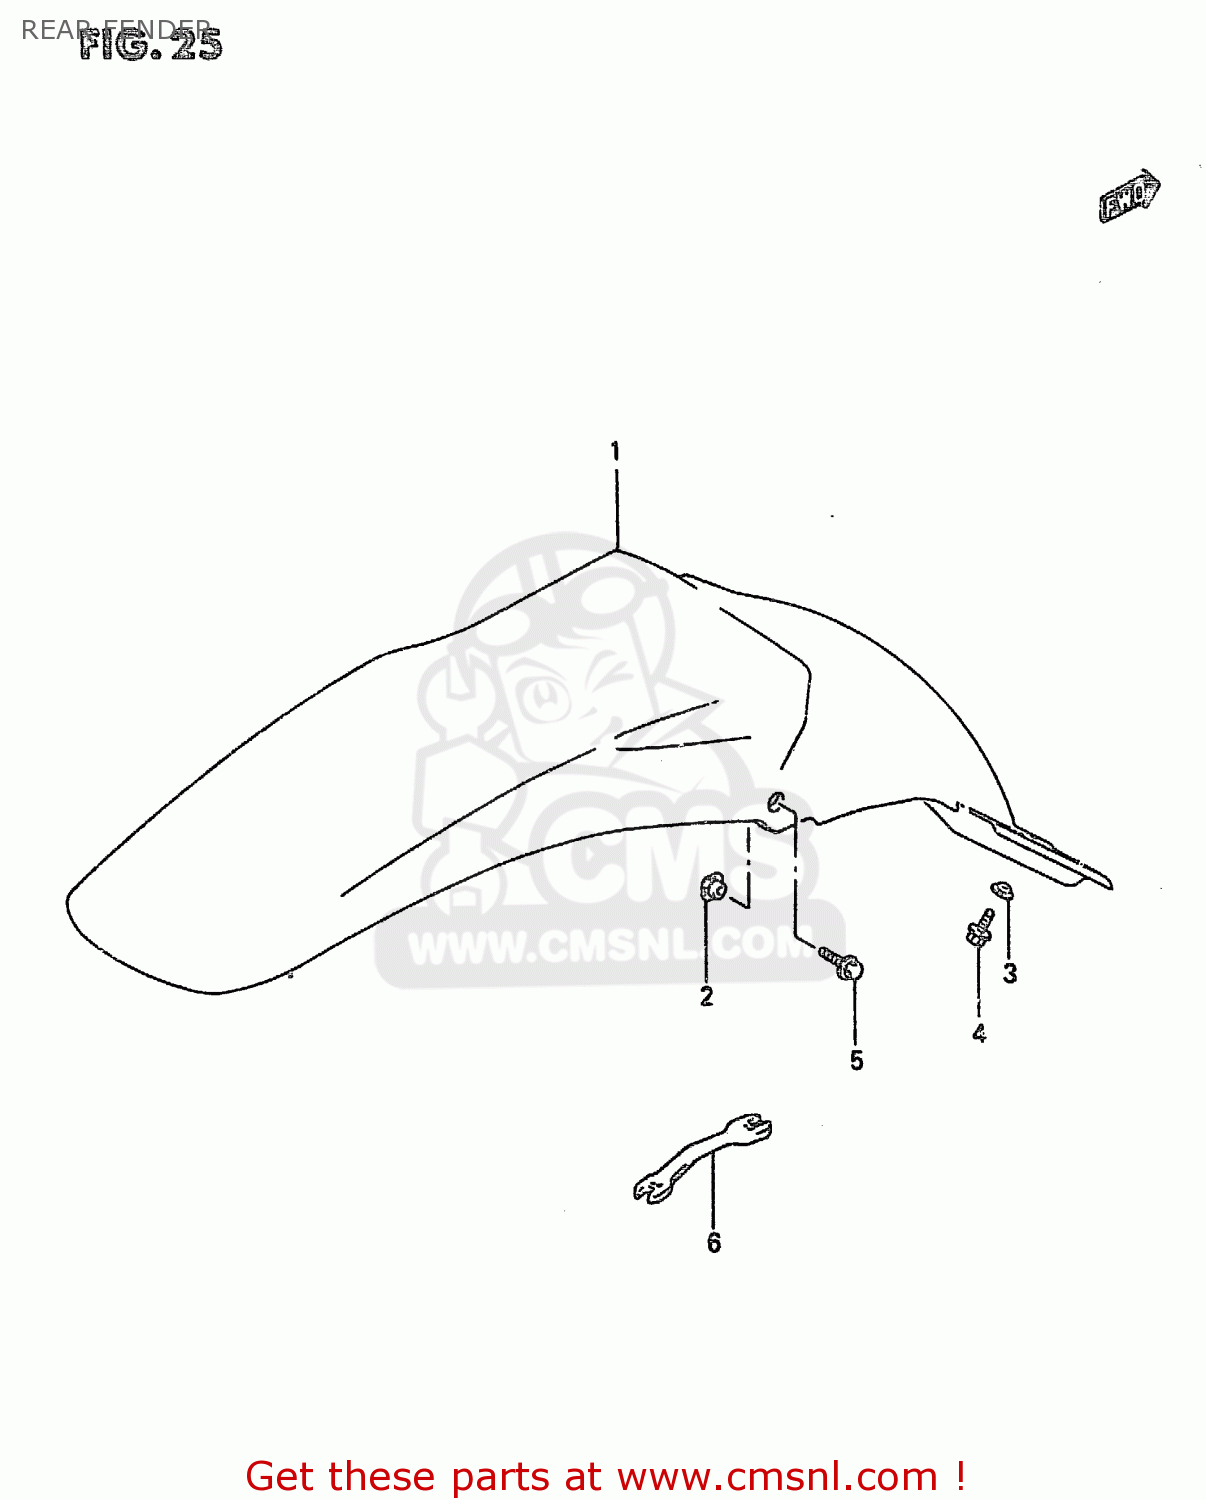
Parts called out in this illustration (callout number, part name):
1	FENDER,RR
2	NUT
3	WASHER
4	BOLT
5	BOLT
6	SPANNER,OPEN
